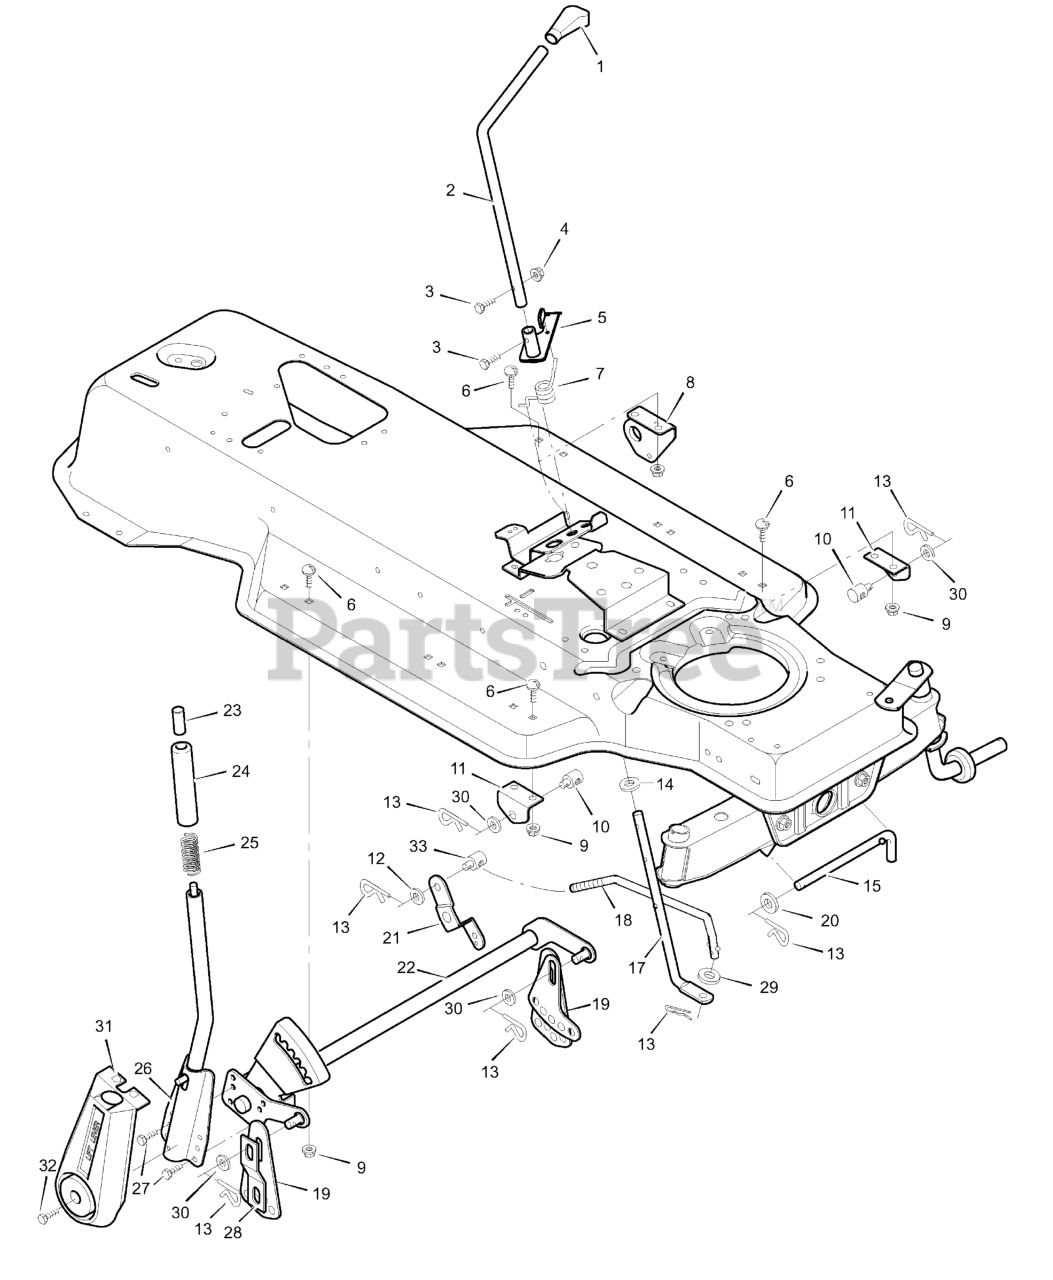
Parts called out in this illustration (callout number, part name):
1	Grip
2	Control, Blade Rotation
3	Screw, Hex
4	Locknut, Hex
5	Lever Assembly, Switch
6	Bolt, Carriage
7	Spring, Torsion
8	Bracket, Rear Hanger
9	Nut, Flange
10	Nut, Adjusting
10	NUT, Adjusting, 1/2-13
11	Bracket, Adjuster Rod
13	Pin, Hair
14	Washer
15	Pin, Pull
17	Lever, Lower Blade Control
18	Rod, Blade Control
19	Plate, Adjuster
19	Plate, Adjuster (2)
21	Bracket, Pivot
22	Lifter Assembly
23	Button, Push
25	Spring, Compression
26	Handle Assembly
28	Link, Suspension
29	Washer
31	Cover, Lift Lever
33	Nut, Adjusting
